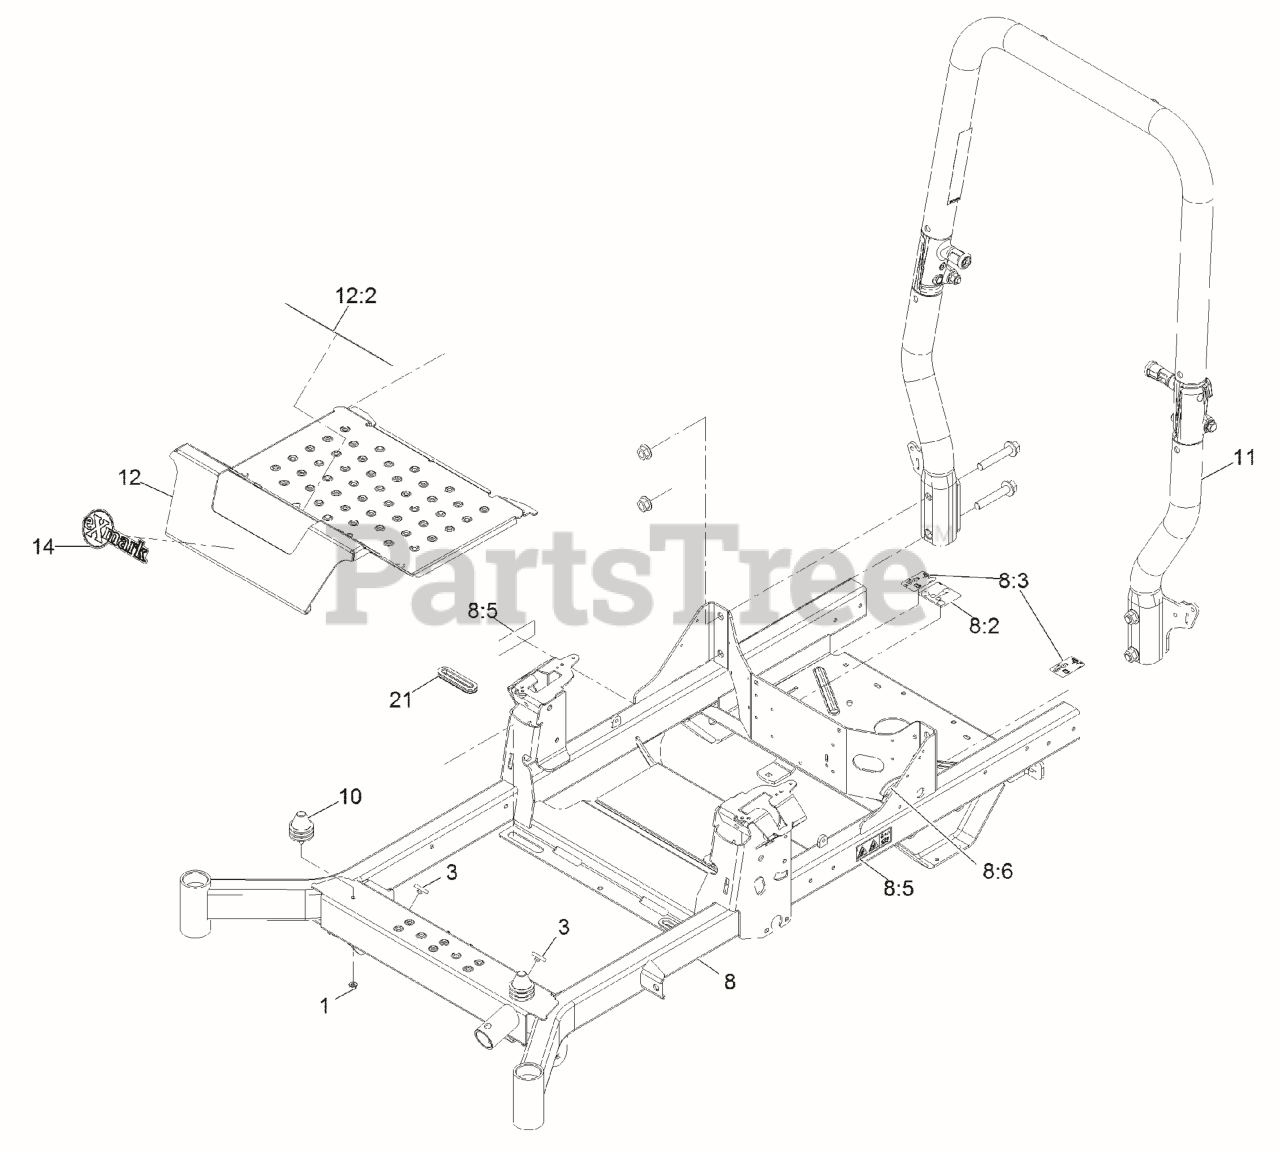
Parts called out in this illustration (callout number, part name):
1	NUT-HF, NI
2	BEARING-BALL
3	BUMPER-PUSH-IN, RUBBER
4	CAP-GREASE
5	WHEEL AND TIRE ASM
5:1	WHEEL RIM 12X8.5
5:2	TIRE
5:3	Stem-Valve
8	FRAME ASM
8:2	DECAL-ROUTING, BELT
8:3	DECAL-RELEASE, DRIVE
8:4	Decal-Patent Ttco.Com
8:5	DECAL-WARNING
8:6	STRIP-SEAL
9	ASM-Front Caster W/Fork
10	ISOLATOR
11	ASM-ROPS TAPERED
12	PAN-FLOOR
12:2	DECAL-DANGER
14	DECAL-EXMARK LOGO
15	NUT-LUG
17	SCREW-HHF
18	WASHER-FLAT
21	GROMMET-RUBBER
